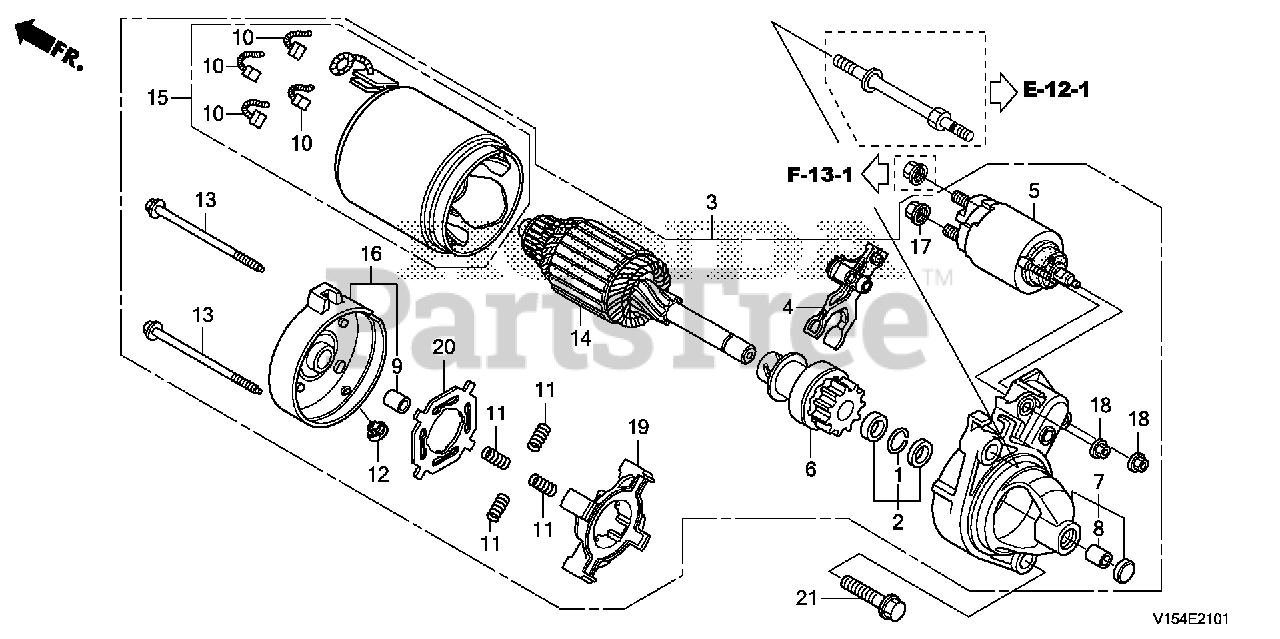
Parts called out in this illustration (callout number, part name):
1	RING, SNAP (DENSO)
2	COLLAR SET, CLUTCH STOP
3	STARTER MOTOR ASSY.
4	LEVER, PINION DRIVE
5	SWITCH ASSY., MAGNET
6	CLUTCH, OVERRUNNING
7	HOUSING, DRIVE SIDE
9	BEARING B
10	BRUSH
11	SPRING, BRUSH
13	BOLT, THROUGH
16	FRAME, COMMUTATOR END
17	NUT, HEX. (8MM)
18	NUT, FLANGE (5MM)
19	HOLDER, BRUSH
20	INSULATOR, BRUSH HOLDER
21	BOLT, FLANGE (10X40)
